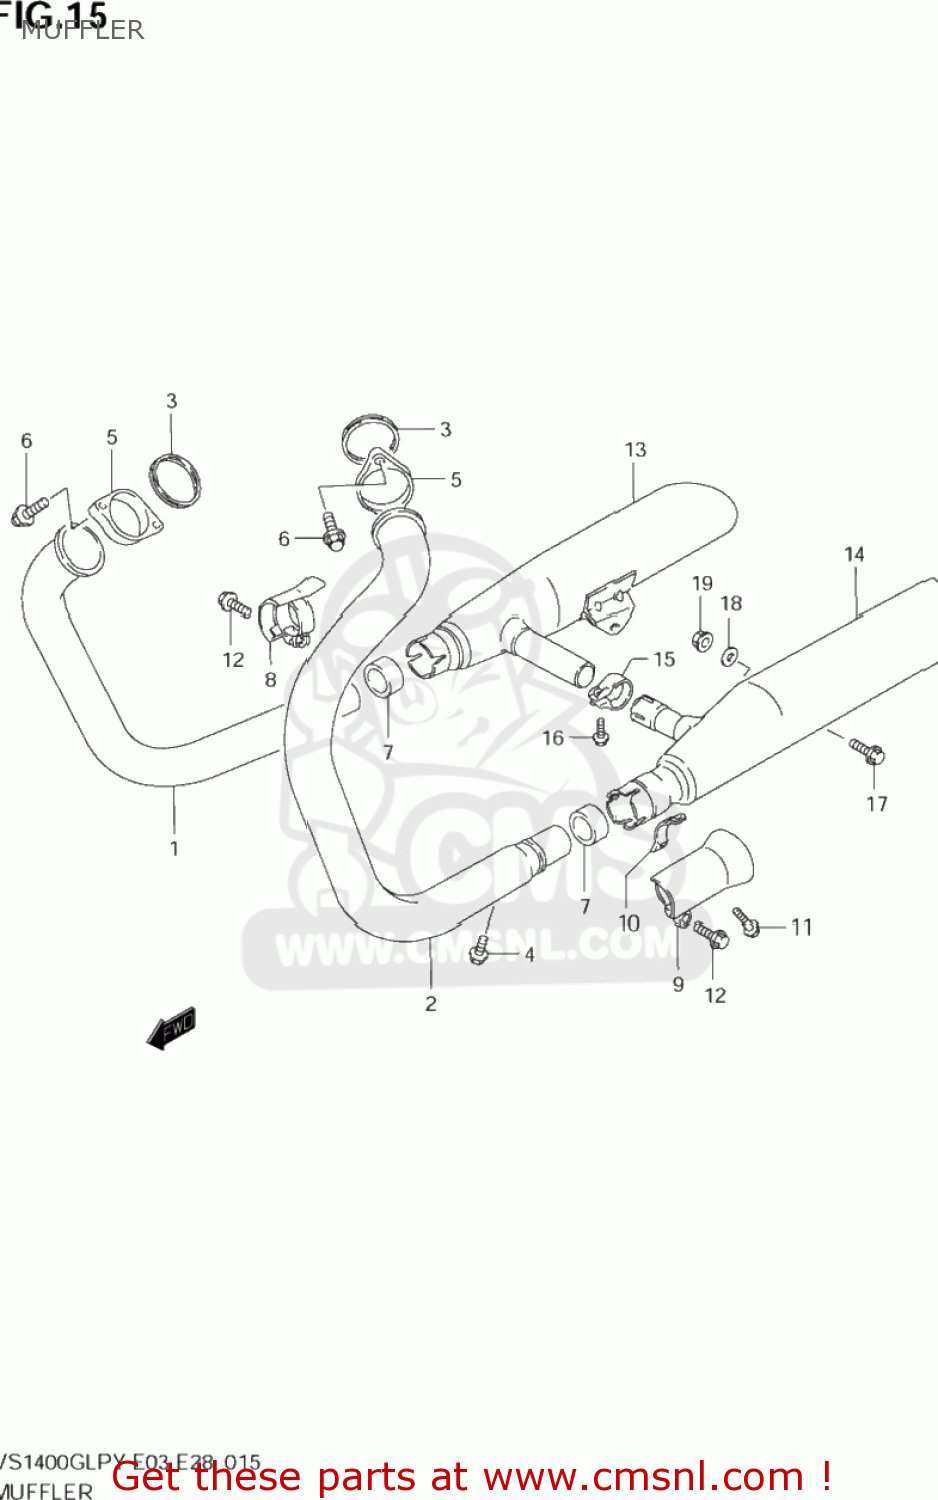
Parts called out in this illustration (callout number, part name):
1	PIPE,EXHAUST,R
2	PIPE,EXHAUST
3	GASKET,EXHAUST PIPE (NAS)
4	BOLT
5	CLAMP,EXHAUST PIPE
6	BOLT(8X35)
7	CONNECTOR,MUFFLER
8	CLAMP,CONNECTOR,R
9	CLAMP,CONNECTOR,L
10	CLAMP,MUFFLER COVER
11	BOLT
12	BOLT(8X35)
13	BODY,MUFFLER,R
14	BODY,MUFFLER,L
15	CLAMP,EXHAUST COUPLER
16	BOLT
17	BOLT
18	WASHER
19	NUT
